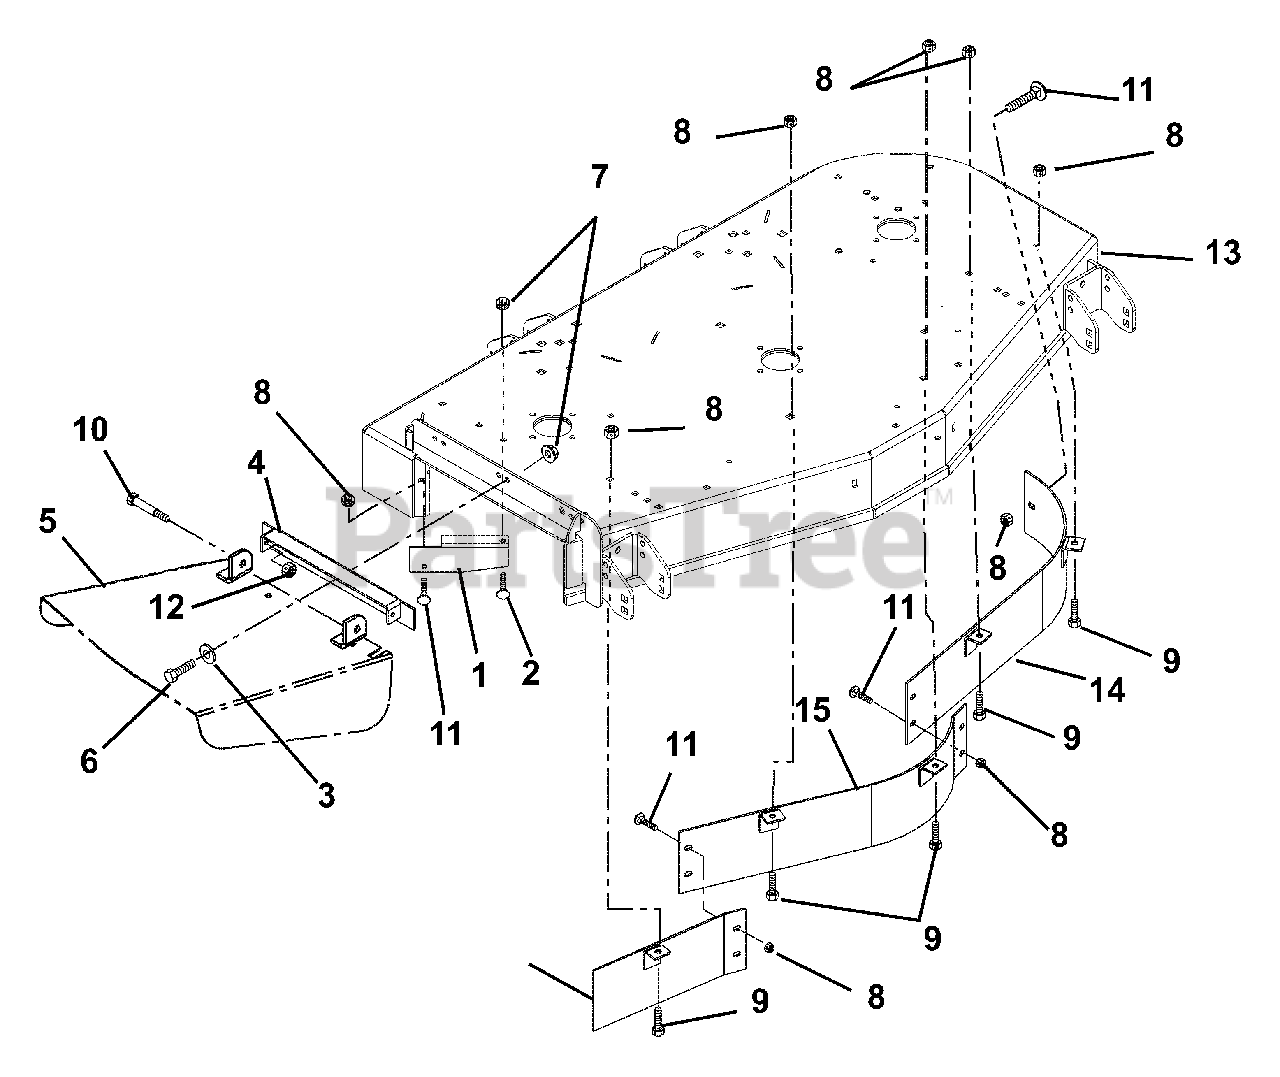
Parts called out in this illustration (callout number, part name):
1	DEFLECTOR - 52"/34"
1	DEFLECTOR, 60" (BLACK)
2	@BLT-RDHDSQNK .38-16X1.00 G5YZ
3	@WSHR-FL-STL.38X.875X.083 YWZC
4	WMT, DISCH CHUTE BRKT - ORANGE
4	WMT, CHUTE BRKT
5	DISCH CHUTE - ORANGE
5	WMT, 60" DISCHARGE CHUTE
6	@BLT-HEX .38-16X1.00 GR5 YWZC
7	@NUT-LK-TOP-FLG .38-16 YWZC
8	@NUT-LK-TOP-FLG .31-18 YWZC
9	@BLT-HEX .31-18X.75 GR5 YWZC
10	BLT-SHLDR .38-16X.38 SKH
11	@BLT-RDHDSQNK .31-18X.75 G5YZ
12	@NUT-LK-CTR .38-16 YWZC
13	WMT, 52" MOWER DECK - ORANGE
13	60" 7 GA. MOWER DECK - ORANGE
14	BAFFLE - LEFT FRONT - 52"
14	BAFFLE - LEFT FRONT - 60"
15	BAFFLE - CENTER FRONT - 52"
15	BAFFLE - CENTER FRONT - 60"
16	BAFFLE - RIGHT FRONT - 52"
16	BAFFLE - RIGHT FRONT - 60"
